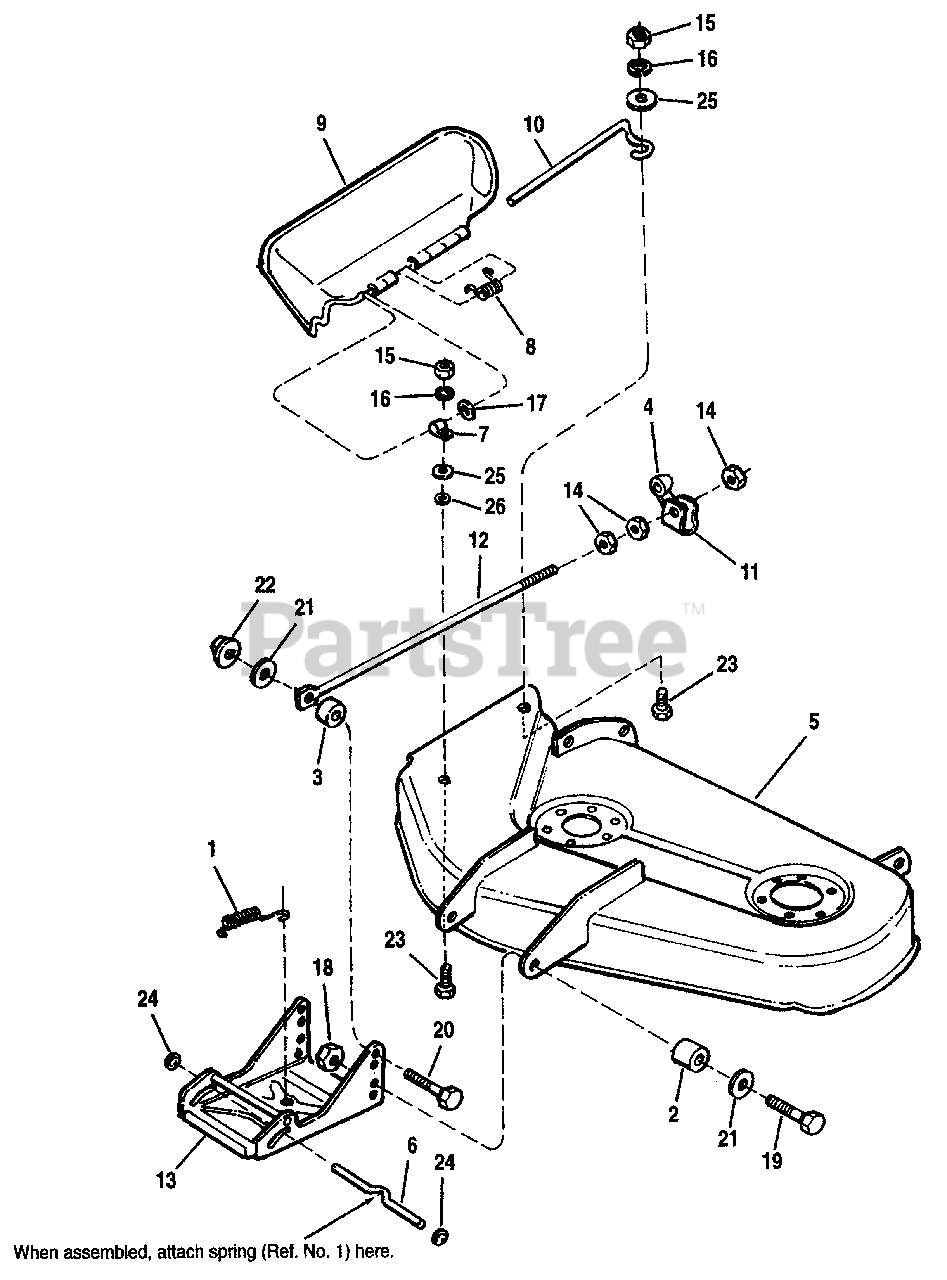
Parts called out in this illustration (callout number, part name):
4	SPACER
5	HOUSING ASSY., 34" (Orange)
5	HOUSING ASSY., 34" (Black)
6	ROD, Latch, Hitch
9	DEFLECTOR, Plastic
10	ROD, Deflector, Front
12	ROD, Adjustment
13	HITCH ASSY.
14	JAMNUT, Hex, 1/2-13
15	NUT, Hex, 1/4-20
16	LOCKWASHER, 1/4
17	WASHER, Flat, 5/16
18	LOCKNUT, Hex, 3/8-16
19	CAPSCREW, Hex Hd., 3/8-16 x 1-1/4
20	CAPSCREW, Hex Hd., 3/8-16 x 1
21	WASHER, Flat, 3/8
22	NUT, Hex, Flange Lock, 3/8-16
23	CARRIAGE BOLT, 1/4-20 x 7/8
24	PUSHNUT
25	WASHER, Flat, 17/64 x 27/32 x 1/8
26	PUSHNUT
